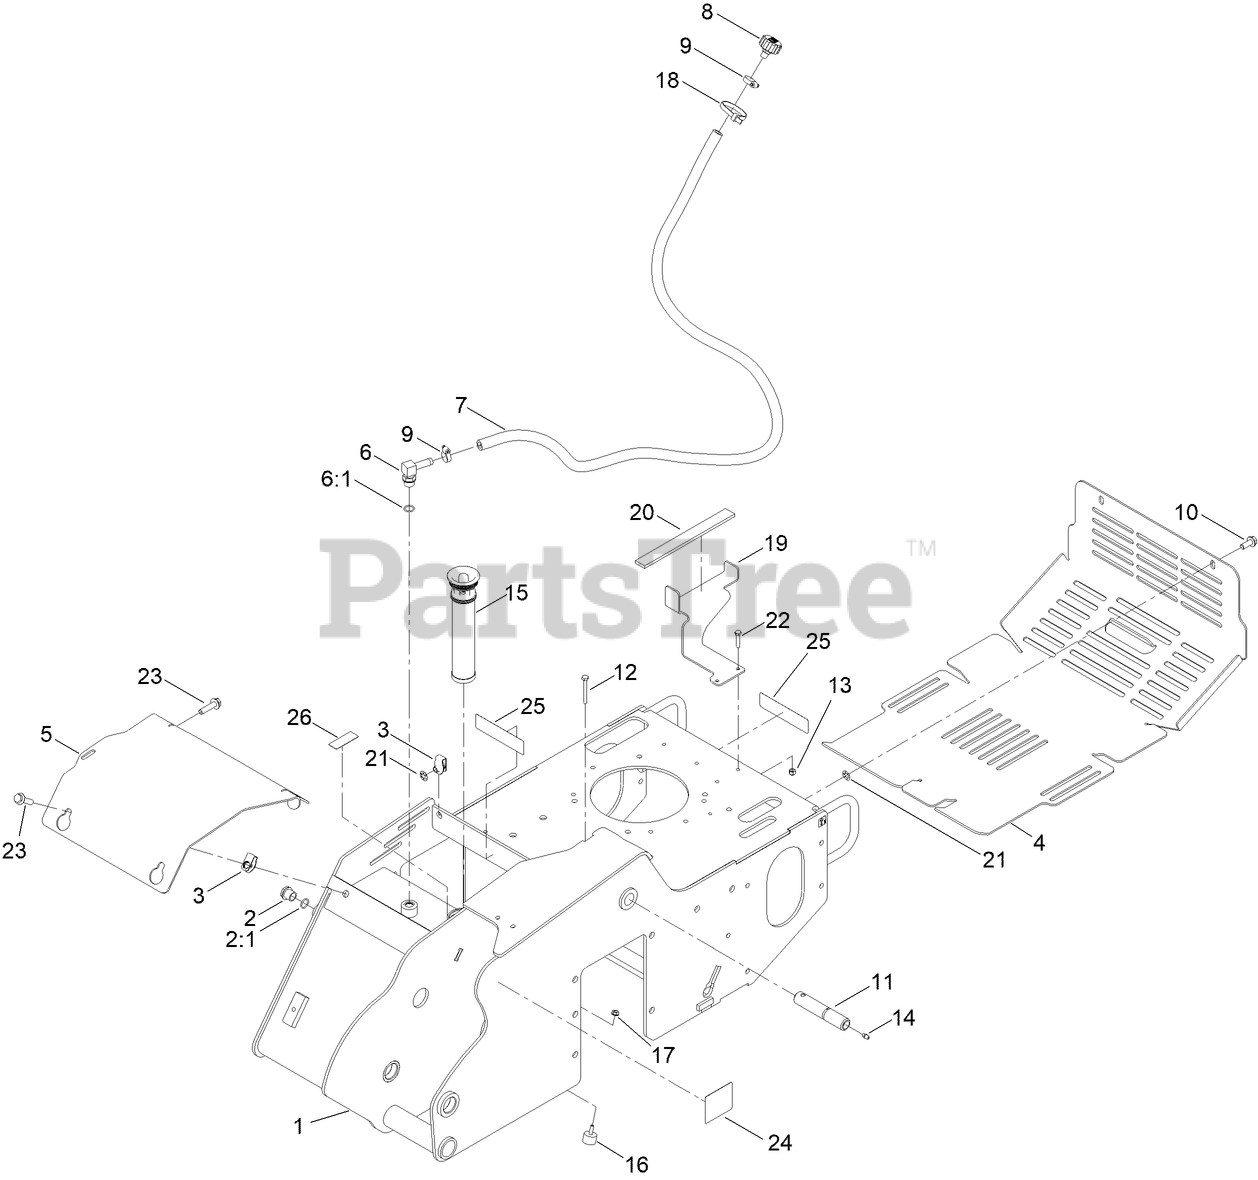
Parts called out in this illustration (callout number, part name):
1	MAIN FRAME ASM, [505-164]
2	SIGHT GLASS ASM
2:1	O-RING
3	NUT-CLIP, U
4	COVER-REAR
5	PLATE-COVER, FRONT
6	FITTING-ELBOW, 90
6:1	O-RING
7	HOSE-BREATHER
8	BREATHER
9	CLAMP-HOSE
10	SCREW-HHF
11	PIN-PIVOT
12	SCREW-HH
13	NUT-LOCK, NI
14	FITTING-GREASE
15	IN-TANK FILTER ASM
16	BUMPER
17	NUT-HF
18	TIE-CABLE
19	BRACKET-TANK
20	PAD-FOAM
21	NUT-PUSH
22	SCREW-HH
23	SCREW-HHF
24	DECAL-WARNING
25	DECAL-DANGER
26	DECAL-OIL, HYD
